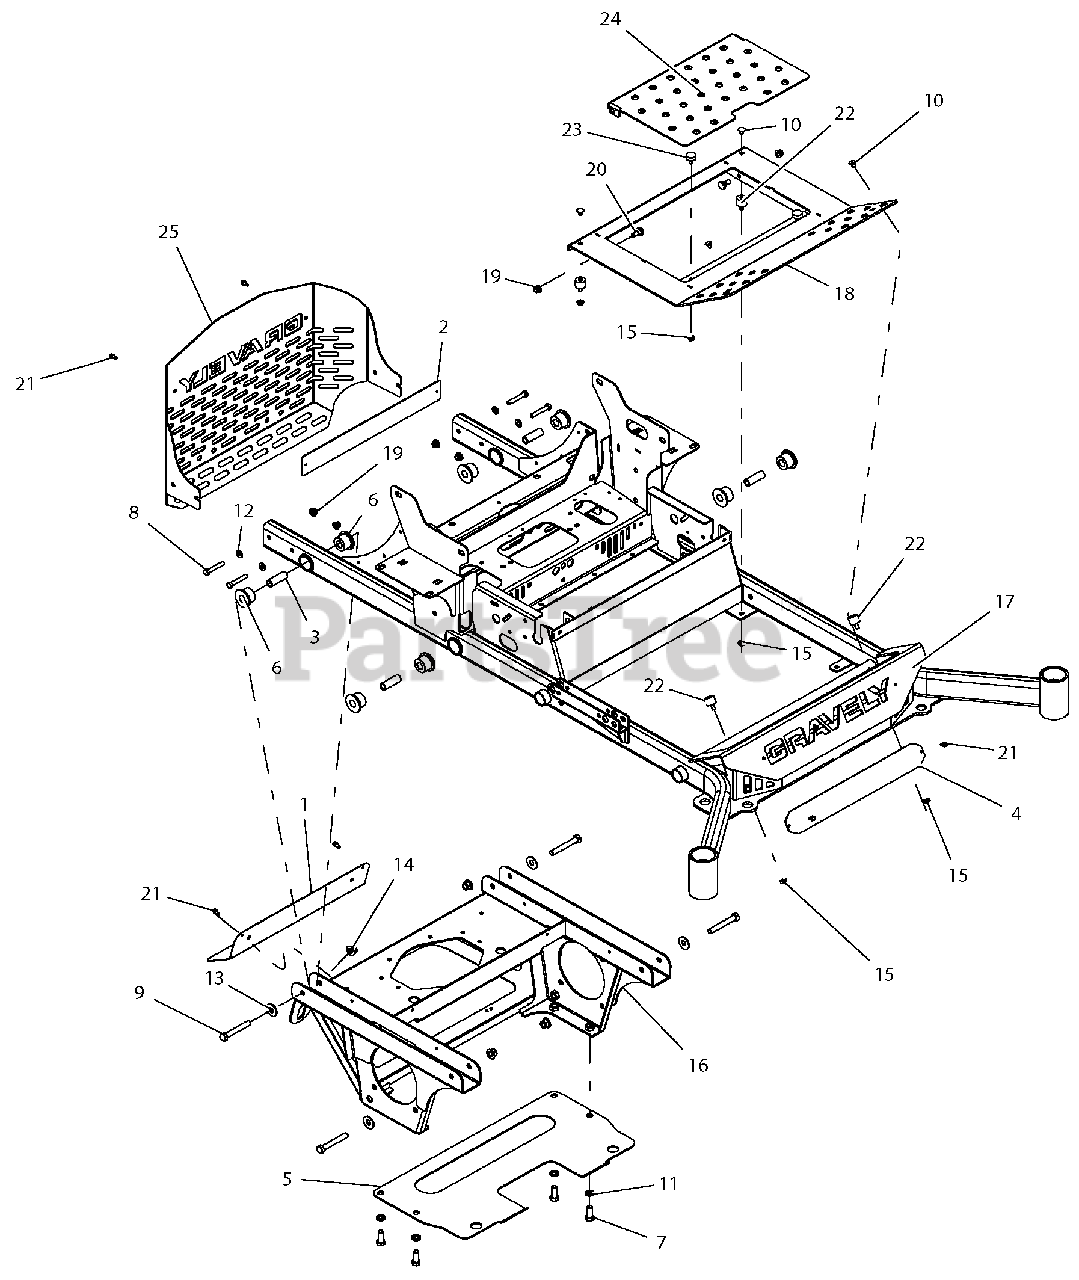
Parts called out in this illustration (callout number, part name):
1	SHIELD, MUFFLER HEAT
2	PLATE, BUMPER PRO-TURN 200-BLACK
3	SPCR, .50 X .75 X 2.23 YZ
4	PLATE, BUMPER LOGO BACKING-BLACK
5	PLATE-TRANSMISSION SKID-RED
6	BSHG, FLANGE .750 X 1.510 X 1.130 X 2.000
7	BLT-HEX .50-13X1.25 GR5 YWZC
8	BLT-HEX .38-16X2.25 GR5 YWZC
9	BLT-HEX .50-13X3.50 GR5 YWZC
10	BLT-RDHDSQNK .31-18X.50 G5 YWZC
11	WSHR-LK .50X.125 REG YWZC
12	WSHR-FL-STL.406X.812X.065 YWZ
13	WSHR-FL-STL.563X1.38X.109YWZC
14	NUT-LK-NYL-FLG .50-13 YWZC
15	@NUT-SPNLK-FLG .312-18 YWZC
16	WLDT, 200 PT AXLE/ENGINE FRAME
17	72" PT200/400 MAIN FRAME WITH SAFTEY DECALS
18	FOOTPLATE WLDMT W/SAFETY DECAL
19	NUT-LK-NYL-FLG .38-16 YWZC
20	BLT, SHLDR EP .38-16X.30 HEX YZ
21	SCR-TAP .25-20X.50 HWH TR YWZ
22	BUMPER, STUD MOUNTED W/FEMALE INSERT
23	BUMPER, RUBBER
24	INSPECTION PANEL W/SAFETY DECAL
25	PRO-TURN 200 REAR BUMPER W/ SAFETY DECALS
